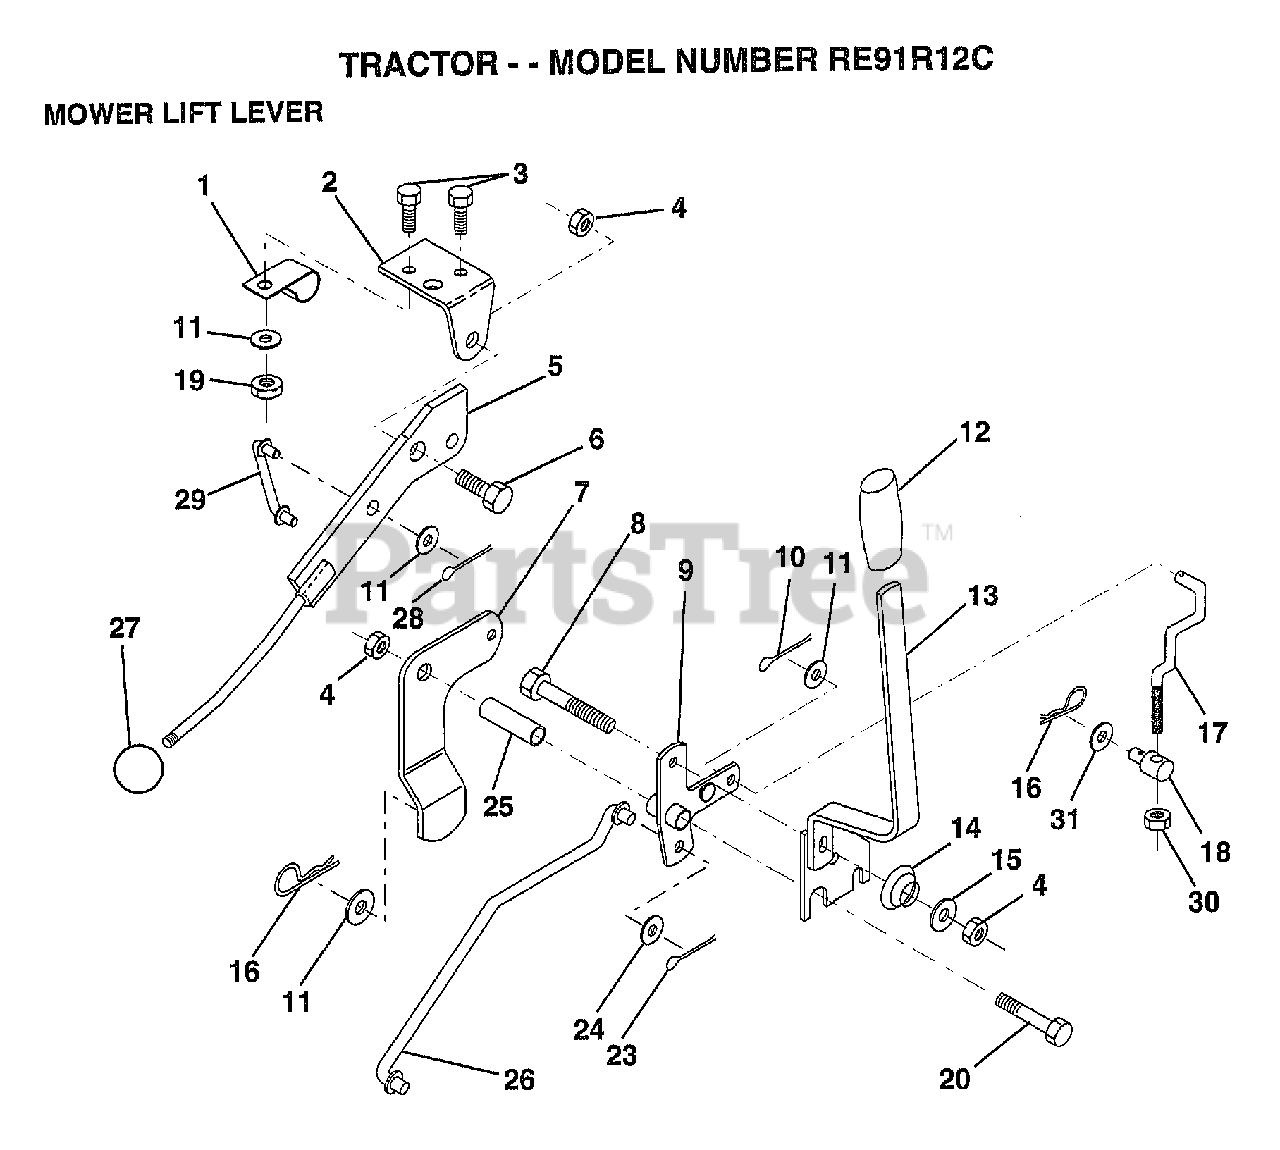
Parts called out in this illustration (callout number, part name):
1	"CLIP,INSULATOR"
2	BRKT CLUTCH
3	BOLT HXHD FIN
5	LEVER.ASM.CLUTCH
6	"BOLT, SHOULDER LT"
7	MWR CLUTCH ARM AS
8	BOLT
9	"BELLCRANK,LIFT"
10	COTTER PIN
11	WASHER
13	HANDLE.ASM.LIFT
14	SPRING COMPRESSIO
15	WASHER T
16	SPRING.RETAINER
17	"LINK,LIFT FRT"
18	TRUNION ADJ
20	BOLT
23	PIN COTTER 1/8
25	TUBE SPACER
26	ROD LIFT MOWER
27	KNOB T(3/8 HOLE)
29	CLUTCH LINK
30	NUT
31	WASHER
